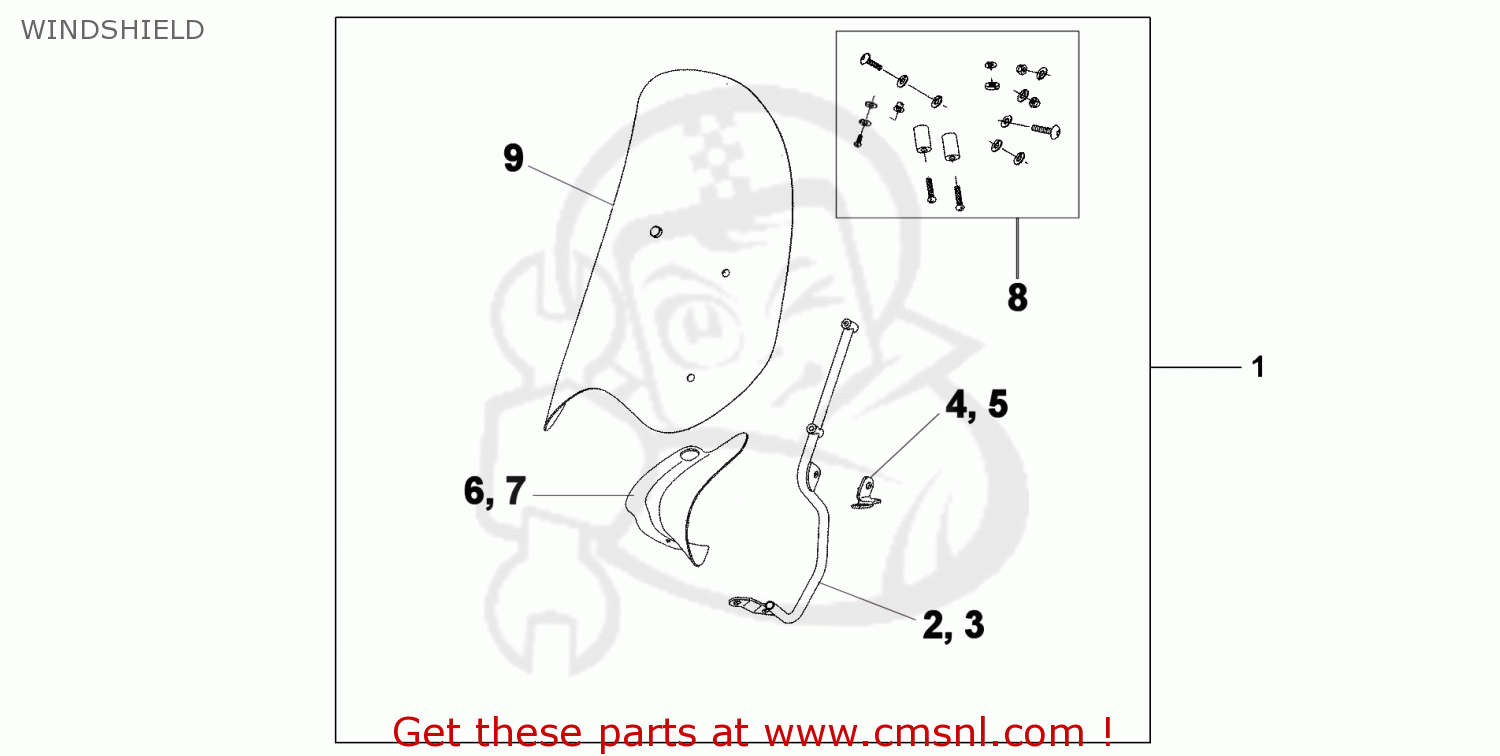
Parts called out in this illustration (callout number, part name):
1	WINDSHIELD
2	RIGHT SCREEN STAY
3	LEFT SCREEN STAY
4	BRACKET A, RIGHT
5	BRACKET A, LEFT
6	RIGHT KNUCKLE DEFLEC
7	LEFT KNUCKLE DEFLECT
8	WINDSHIELD SUB KIT B
9	SHIELD, WIND
